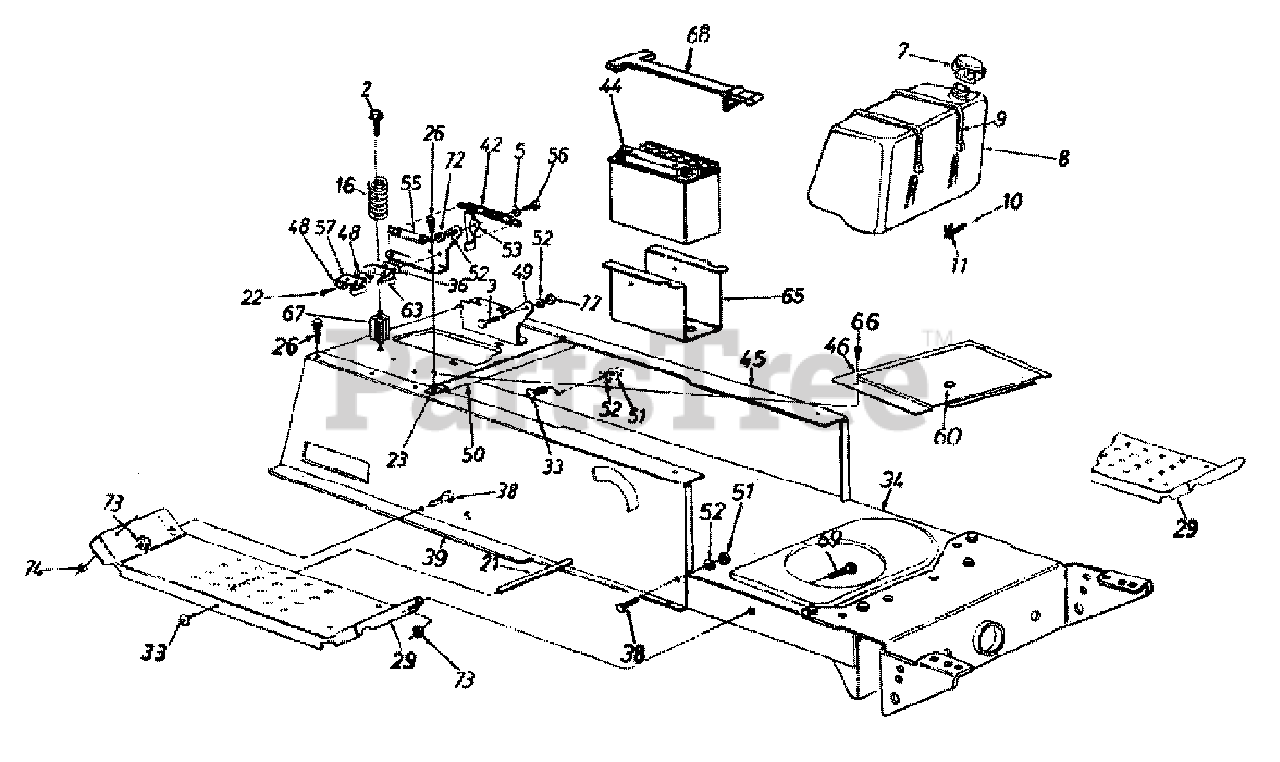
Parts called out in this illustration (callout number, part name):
2	Hex Wash. Hd. Tap Scr.5/16-18 x 3.25" Lg.
3	Shld. Bolt .437" Dia. x .162"
5	Spr-Wash. .445" I.D. x .75
7	Fuel Cap
8	Fuel Tank
9	Tie Strap
10	Fuel Line
16	Compression Spring
21	Running Board Rod
22	Hex Wash. Hd. AB-Tap Scr.#8 x .50" Lg.
23	Speed Nut #10Z
26	Hex Wash. Hd. AB-Tap Scr.5/16 x .75" Lg.
36	Insulator Boss Plate
38	Hex Bolt 5/16-18 x .75" Lg.
39	Upper Frame-R.H.
42	Extension Spring 5.31" Lg.
44	12-V Battery
45	Upper Frame-L.H.
52	L-Wash. 5/16" I.D.
53	Seat Lift Brkt.
56	Shld. Bolt .437" Dia. x .268"
57	Spring Switch (Seat)
60	Snap Bushing
63	Safety Switch (Seat)
66	Truss Mach. B-Tap Scr.#10 x .5" Lg.
67	Spring Spacer
68	Battery Retainer Strap
69	Hex Bolt 5/16-18 x .75" Lg.
72	Hex Nut 5/16-18 Thd.
73	Hex Sems Nut 5/16-18 Thd.
74	Hex Sems Nut 1/4-20 Thd.
